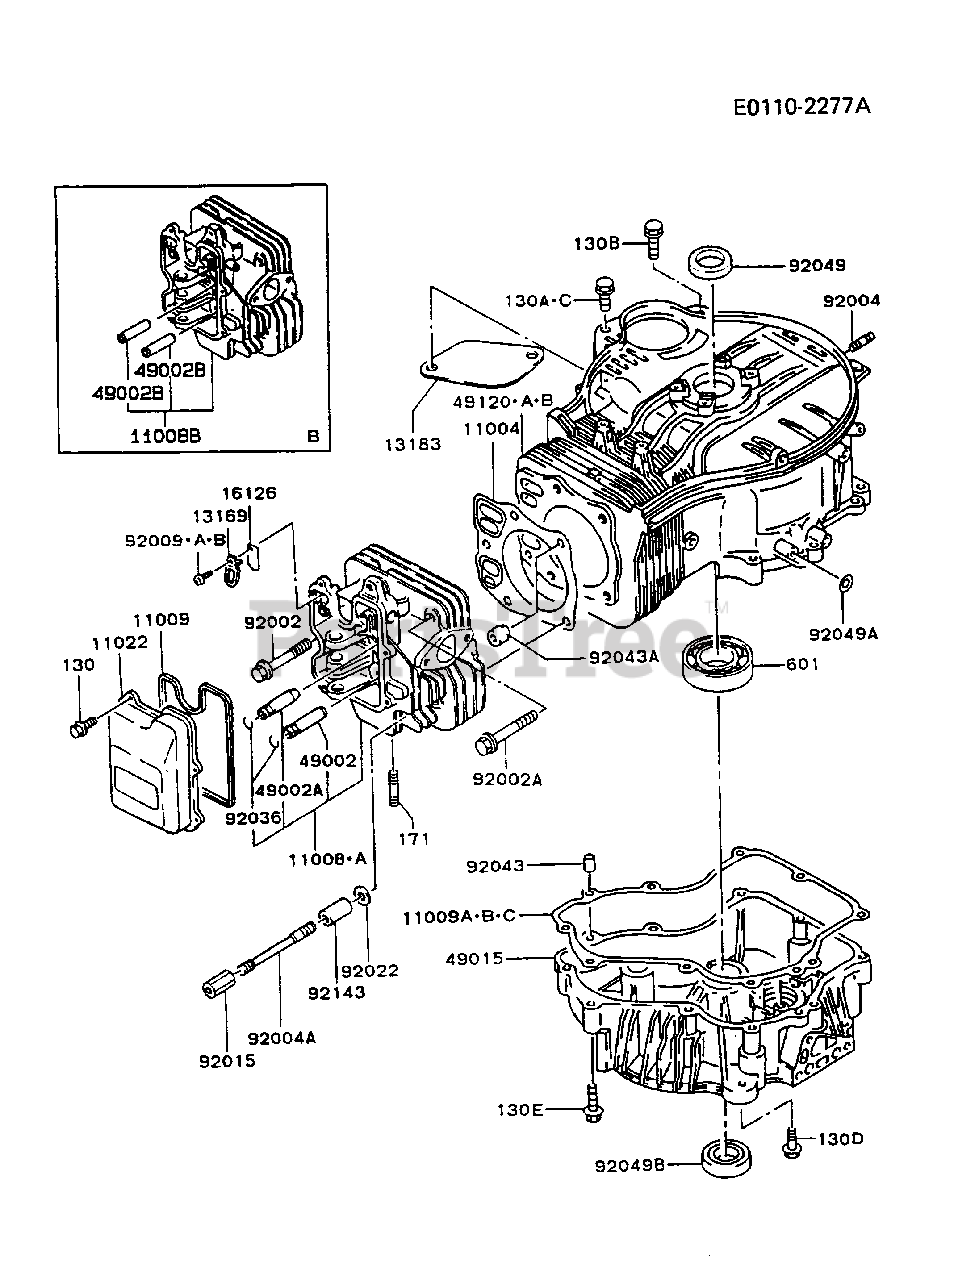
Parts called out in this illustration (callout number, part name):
130	BOLT-FLANGED
130B	BOLT-FLANGED
130C	BOLT-FLANGED
130D	BOLT-FLANGED
130E	BOLT-FLANGED
171	BOLT-STUD
601	BEARING,BALL
